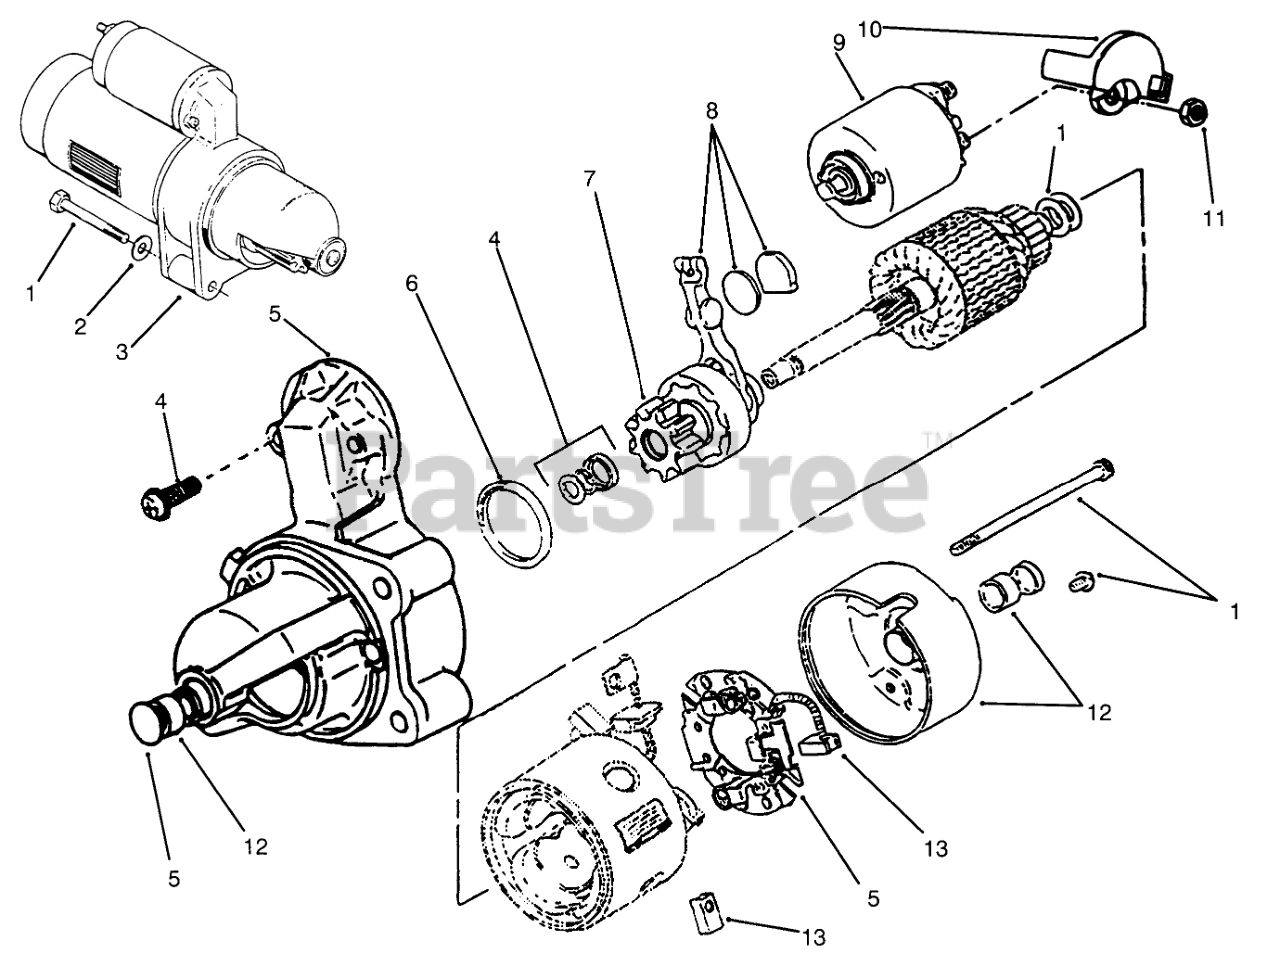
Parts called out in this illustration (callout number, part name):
1	SCREW
2	WASHER
3	STARTER
4	Kit-Hardware, Starter (Includes (2) Solenoid Mtg Screws,2 Thru Bolts,Armature Shims,Pinion Collar,Retaining Ring)
5	Kit-Mounting Bracket (incl. Ref. #13)
6	DUST-SEAL KIT
7	Assembly-Clutch,Starter (Includes Pinion Gear)
8	Kit-Shift Lever,Starter(Includes Lever, Wear Plate & Rubber Plug)
9	Kit-Solenoid Starter (Includes Solenoid & Spring Plunger)
10	Cap-Starter Solenoid
11	WASHER-FLAT
12	Kit-Bushing,Starter (Incl. Rear Cap with Bushing & Front Bushing)
13	Kit-Brush,Starter (Includes (2) Negative & (1) Positive Brushes)
